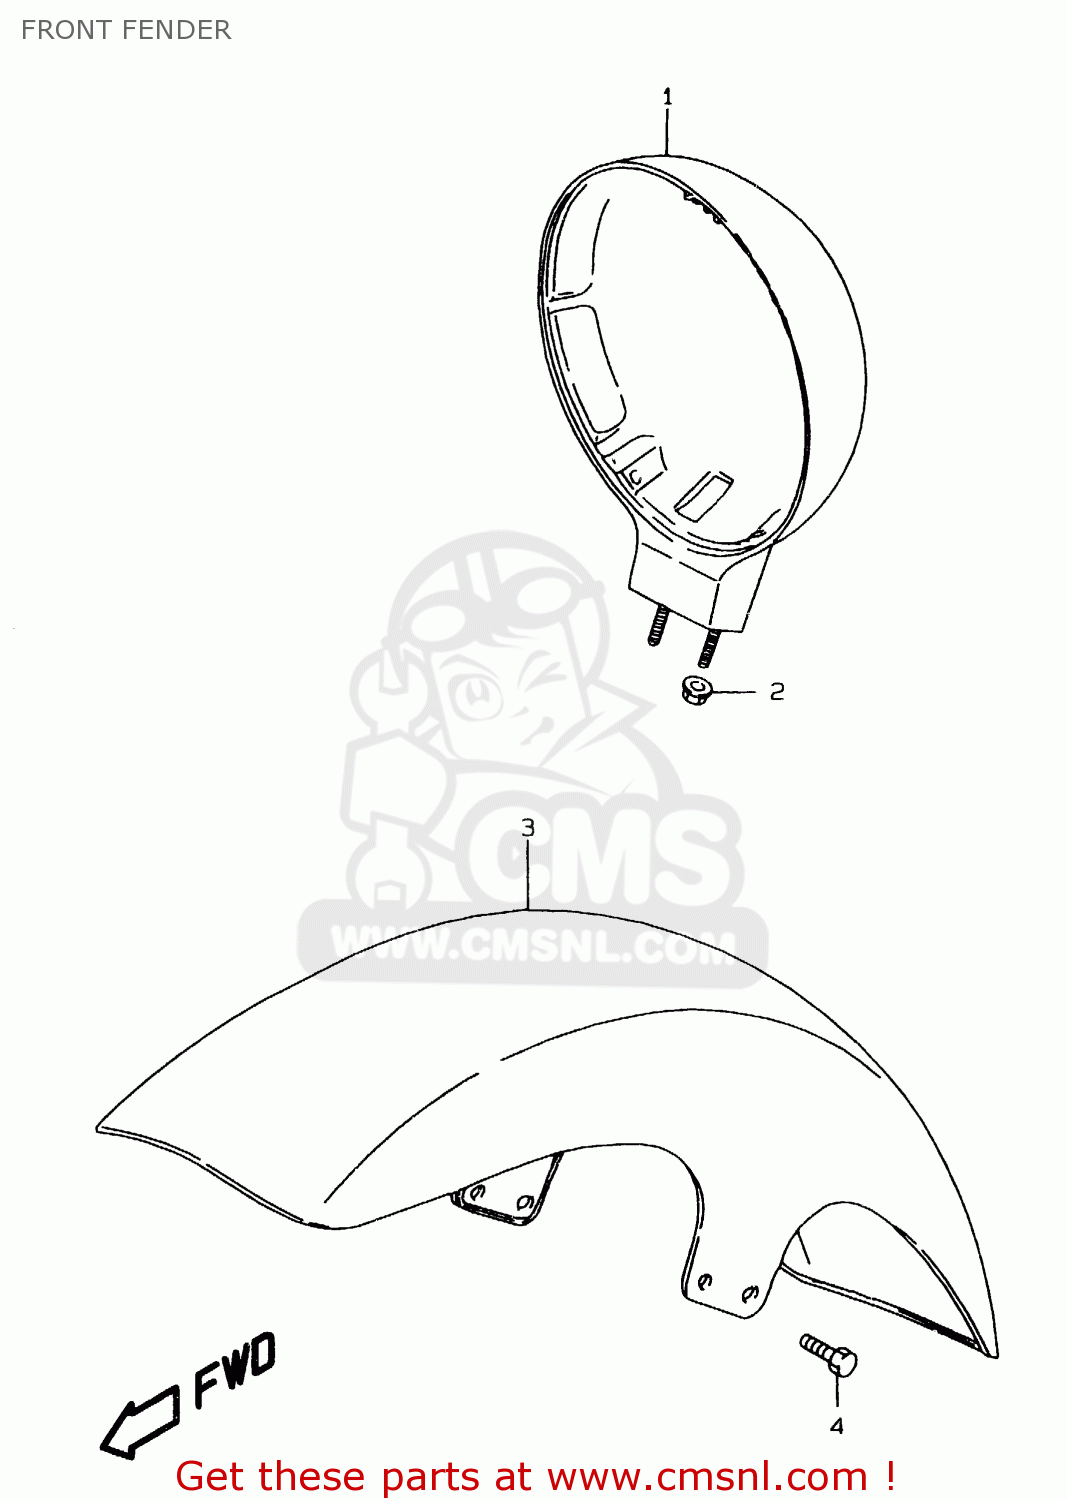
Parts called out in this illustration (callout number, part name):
1	HOUSING,HEADLAMP
2	NUT
3	FENDER,FR
4	BOLT
